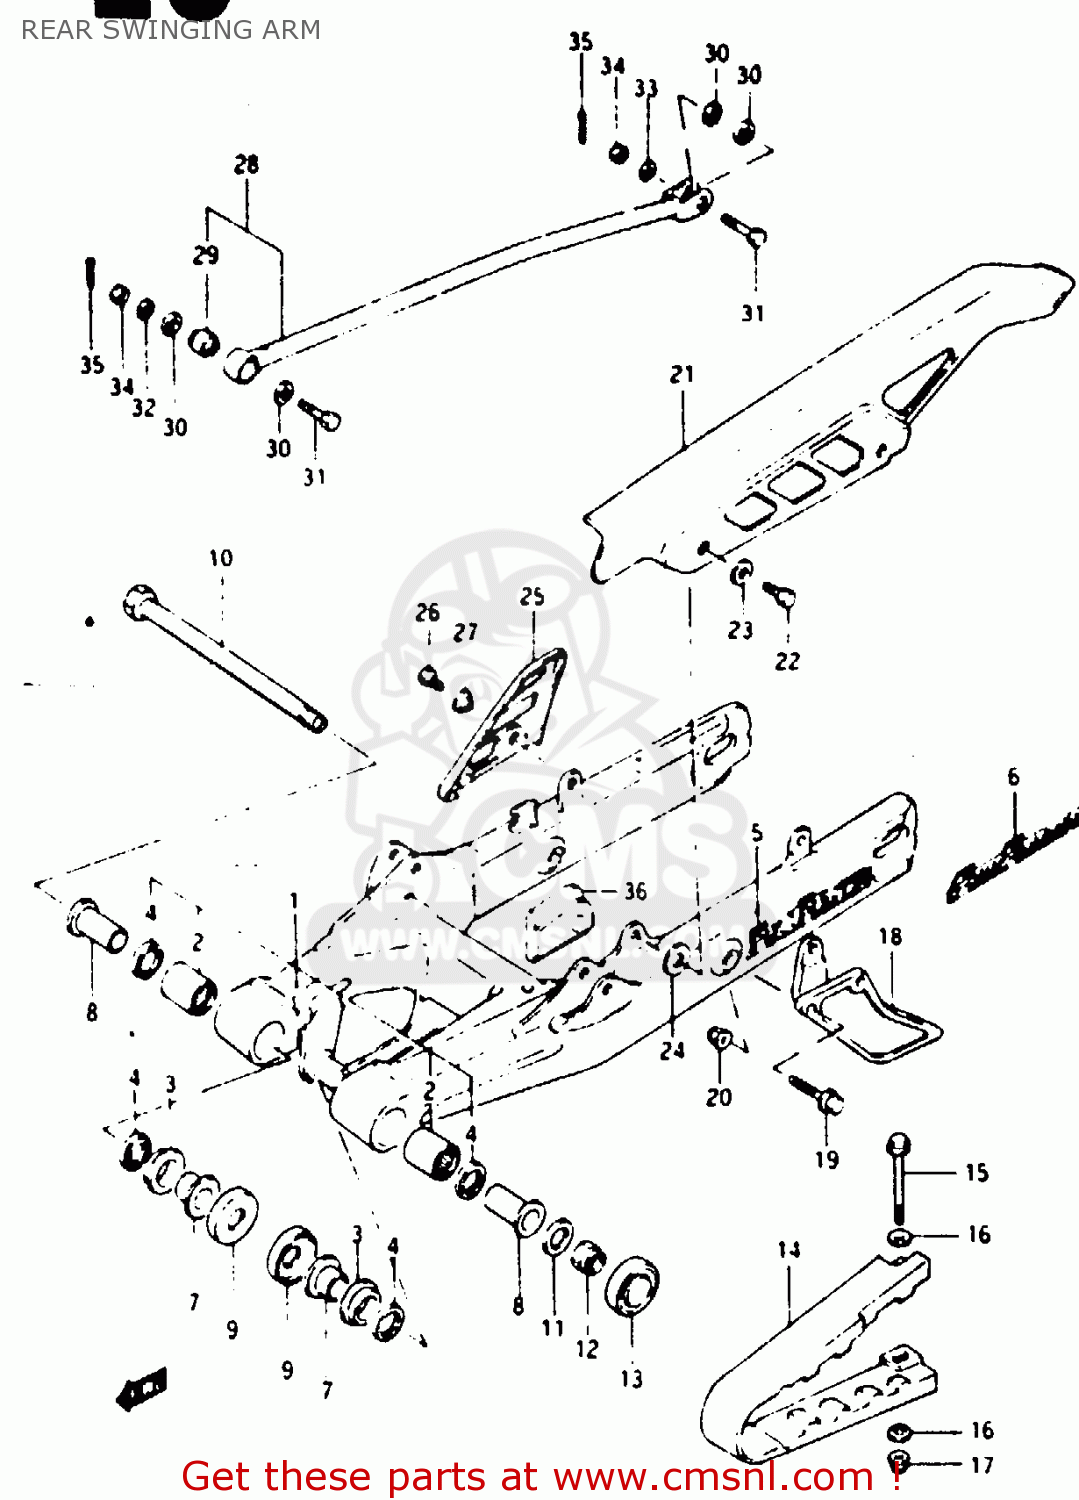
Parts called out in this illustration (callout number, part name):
1	SWINGING ARM ASSY, REAR
2	BEARING(20X27X20)
3	BUSH,RR SWINGINGARM PIVOT
4	OIL SEAL
5	EMBLEM
6	EMBLEM,SWING ARM
7	SPACER,RR SWGARM PIVOT INNER
8	SPACER,RR SWGARM PIVOT
9	COVER,RR SWGARM DUST SEAL
10	SHAFT, SWINGING ARM PIVOT
11	WASHER
12	NUT
13	CAP
14	BUFFER, CHAIN TOUCH DEFENSE
15	BOLT (6X70)
16	WASHER
17	NUT
18	GUIDE, CHAIN
19	BOLT,REAR
20	NUT
21	CASE,CHAIN
22	BOLT
23	WASHER
24	WASHER (6.5X20X1.2)
25	GUARD, FOOT (BLACK)
26	BOLT
27	WASHER
28	TORQUELINK SET
29	SPHERICAL BEARING,TORQUE
30	31
31	BOLT 8X30
32	WASHER (8.5X18X2)
33	WASHER
34	NUT 8MM
35	PIN 20X20
36	GUIDE, CHAIN CASE
